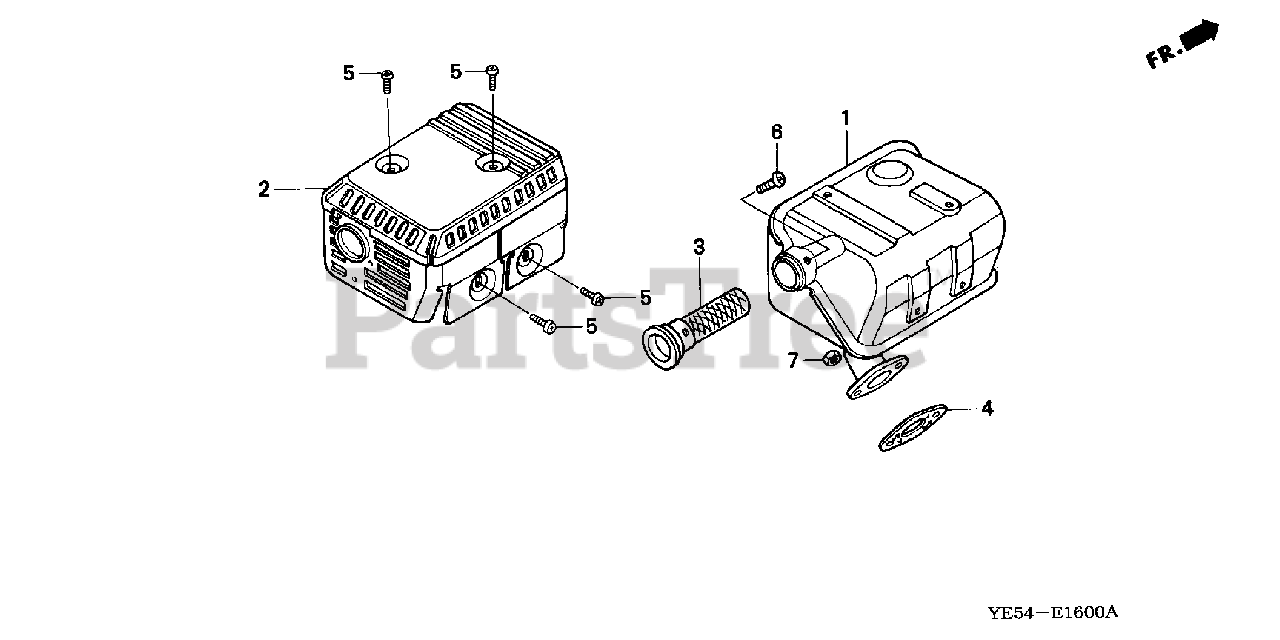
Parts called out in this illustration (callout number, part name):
1	MUFFLER
2	PROTECTOR, MUFFLER
3	ARRESTER, SPARK
4	GASKET, MUFFLER
5	SCREW, TAPPING (5X8)
6	SCREW, TAPPING (4X6)
7	NUT, HEX. (8MM)
